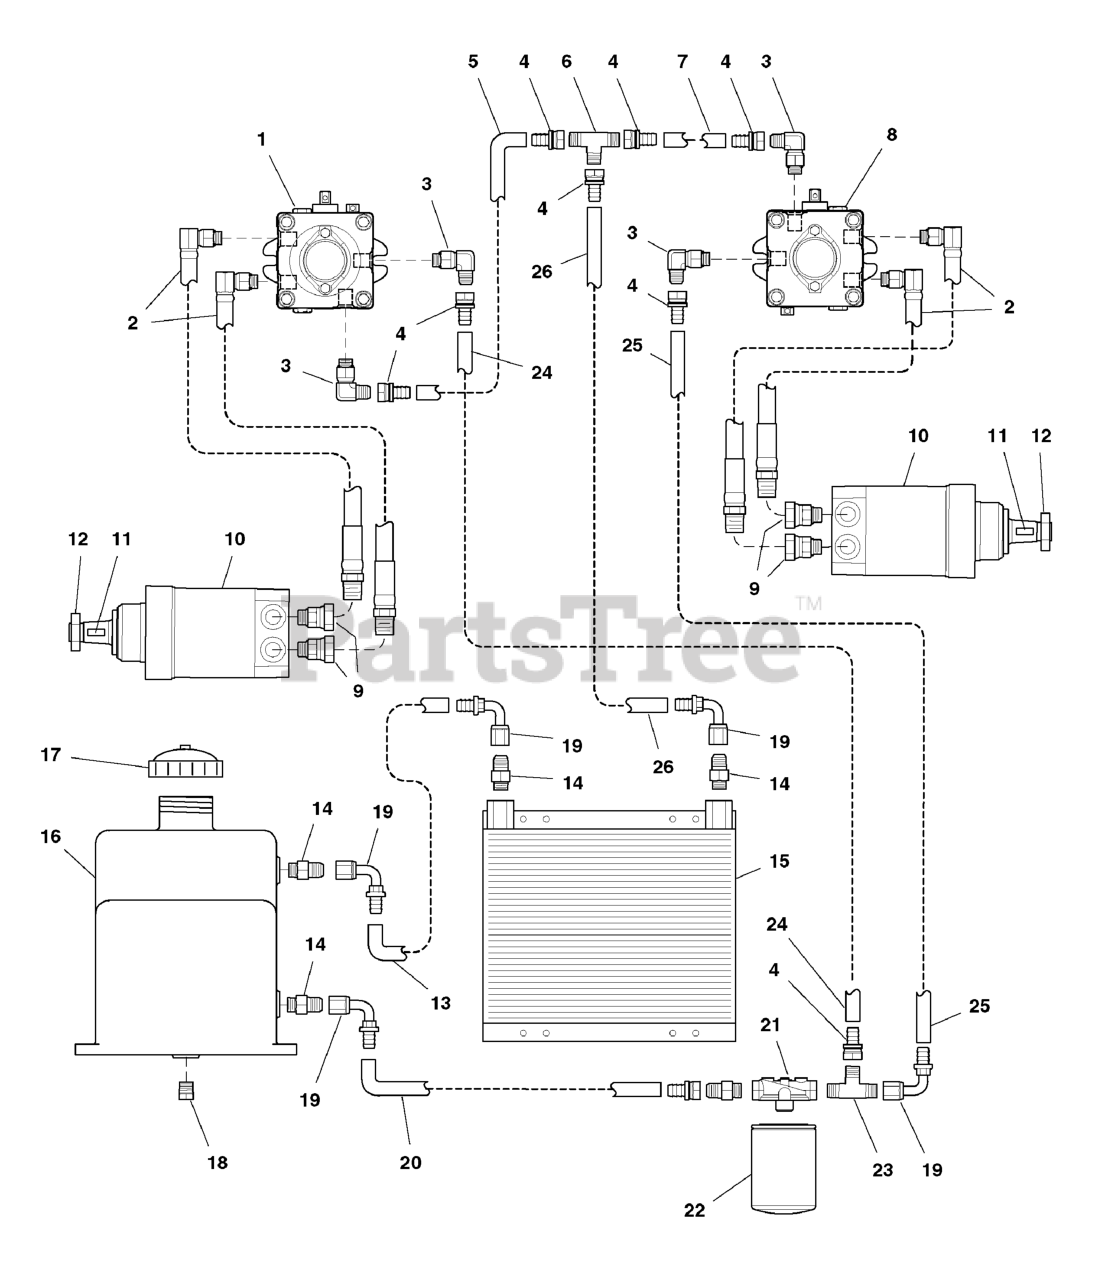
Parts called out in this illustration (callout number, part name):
1	HYDRAULIC PUMP - RH
2	REPLACE WITH 5413138 + 5022599, HYDRAULIC HOSE ASSEMBLY + FITTING
3	FITTING, O-Ring, 90 Deg.
4	FITTING, JIC #8, Straight
5	HOSE, 15" Long
6	FITTING, TEE, JIC #8
7	HOSE, Hydraulic, 27"
8	HYDRAULIC PUMP - LH
9	FITTING, 7/8" O-Ring Straight Swivel
10	HYDRAULIC WHEEL MOTOR, Complete
11	KEY
12	NUT & COTTER PIN
13	HOSE, 16" Long
14	FITTING, NPT - JIC #8
15	OIL COOLER
16	HYDRAULIC OIL RESERVOIR
17	CAP, Reservoir
18	PLUG, 1/2" NPT
19	FITTING, 90 Deg. JIC #8
20	HOSE, 7"
21	FILTER HEAD
22	FILTER, HYDRAULIC, SERVICE PART (PKG)
23	FITTING, TEE, JIC #8, NPT
24	HOSE, Hydraulic, 38"
25	HOSE, Hydraulic, 19"
26	HOSE, Hydraulic, 20"
